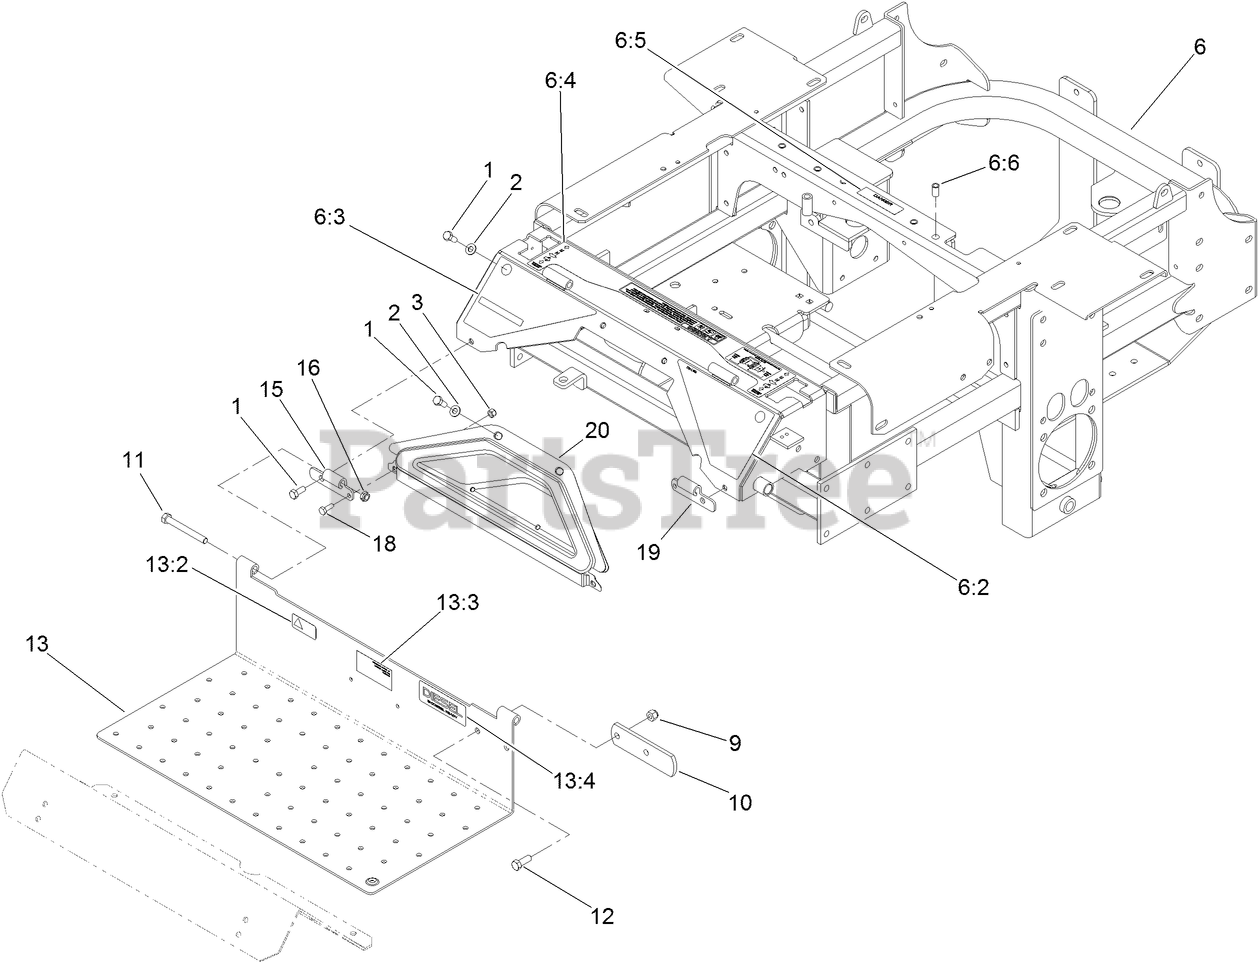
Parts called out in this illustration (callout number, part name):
1	SCREW-HH
2	WASHER-FLAT
3	NUT-LOCK, NI
6	TRACTION FRAME ASM
6:2	Decal-Warning
6:3	Decal-Danger
6:4	DECAL-CONSOLE, TOP
6:5	DECAL-COVER, MISSING
6:6	INSERT-THREADED
9	NUT-LOCK, NI
10	STOP-BRAKE, PARK
11	SCREW-HH
12	SCREW-HH
13	FLOOR PAN ASM
13:2	DECAL-PROTECTION, EAR
13:3	Decal-Location, Manual
13:4	DECAL-DIESEL, BIO-READY
15	Hinge-Floorpan, LH
16	NUT-LOCK, NI
18	SCREW-HH
19	Hinge-Floorpan, RH
20	Pocket
